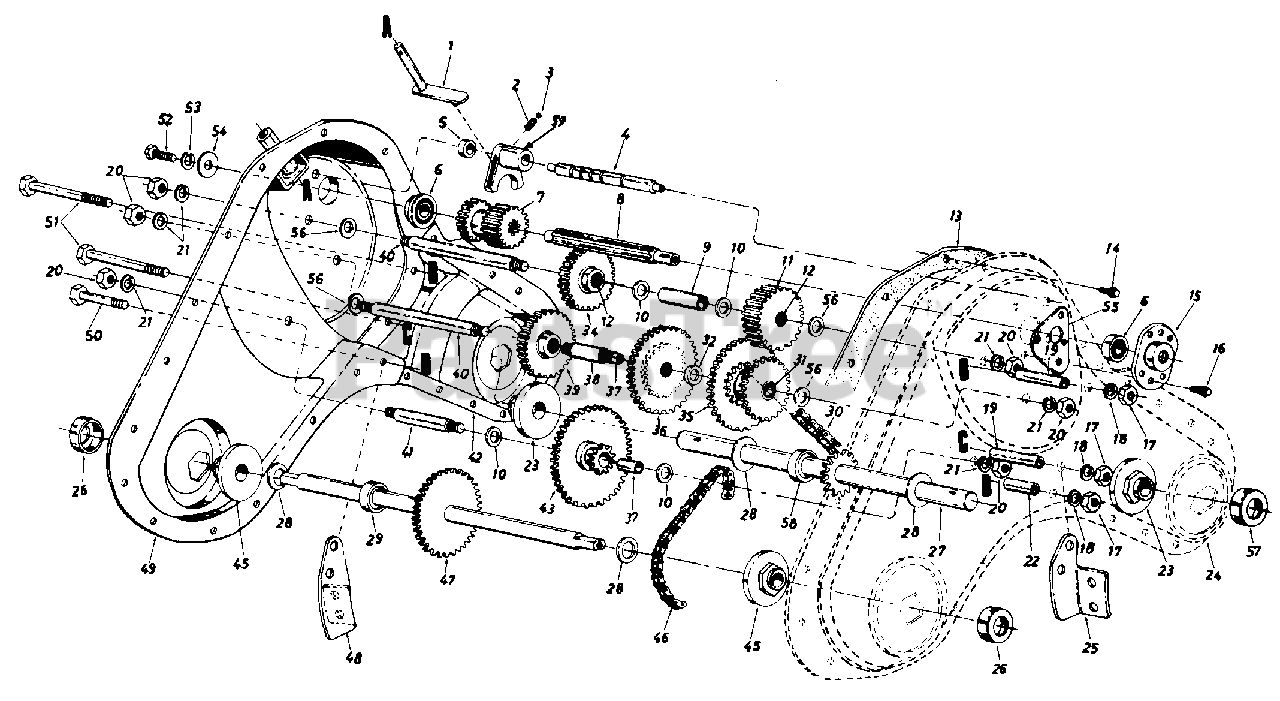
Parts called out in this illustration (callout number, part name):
1	Shifting Bracket Ass'y.
2	Compression Spring .50" Lg.
3	Ball Detent .250" Dia.
4	Detent Shaft 1/2" Dia.
5	Spacer .505" I.D. x .88" O.D.
6	Ball Brg. .62" I.D. x 1.38"
7	Spur Gear 16T
8	Input Spline Shaft 7/8
9	Spacer .657" I.D. x 718" O.D. x 2.85" Lg.
10	Fl-Wash. .640" I.D. x 1.24"
11	Spur Gear 30T 718" I.D. x 11/4 " 0 . D.
12	Needle Bearing 518" I.D. x 718" O.D.
13	Gasket Trans. Hsg.
14	Hex Wash. S-Tap Scr. 1/4-20 x.50" Lg.
15	1-3/8" Dia. Bearing Housing
16	Hex TT-Tap Scr. 1/4-20 x .75" Lg.
17	Hex Nut 5/16-18 Thd.
18	L-Wash. 5/16" I.D.
19	Spacer 1.56" Lg.
20	Hex Nut 7/16-20 Thd.
21	Bell-Wash. .45" I.D. x 1.0"
22	Spacer 1.015" Lg.
23	Tine Shaft Brg. 1.002 x 2.50
24	Trans. Housing Ass'y. L.H.
27	Tine Shaft Ass'y. 1.00" O.D.
28	Thrust Washer 1.030 I.D. x 1.62" O.D.
29	Spacer 1.0" I.D. x .50" Lg.
30	Chain #50 5/8 Pitch x 52 Links Endless
31	Needle Bearing 518" I.D.
32	Fl-Wash. 518" I.D. x 11/4" O.D. x .150
34	Spur Gear 30T 12/16" I.D. x 1/2" W
35	30/44T Gear Ass'y. Comp.
36	Spur Gear 44T
37	Sleeve Bearing
38	Gear Hub 3/4" I.D. x 3.0" Lg.
39	Spur Gear 30T 1.0" I.D. x 1/2" W
40	Jack Shaft 5/8" Dia. x 5.0"
41	Jack Shaft 5/8" Dia. x 2.38"
45	Wheel Brg. .752 x 2.50
46	#420 Chain 1/2 Pitch x 50 Links Endless
47	Wheel Shaft Ass'y. 15.6"
51	Hex Bolt 5/16-18 x 2.50"
52	Hex Bolt 1/4-20 x .62" Lg.
53	L-Wash. 3/8" I.D.
54	Fl-Wash. 1/4" I.D. x .93" O.D.
55	Gear Positioner Bracket
56	Fl-Wash. 7/16" I.D. x 1-3/8" O.D.
57	Dust Cover Ass'y. 1.0" Shaft
58	Spacer .75" I.D. x 2.0" O.D.
